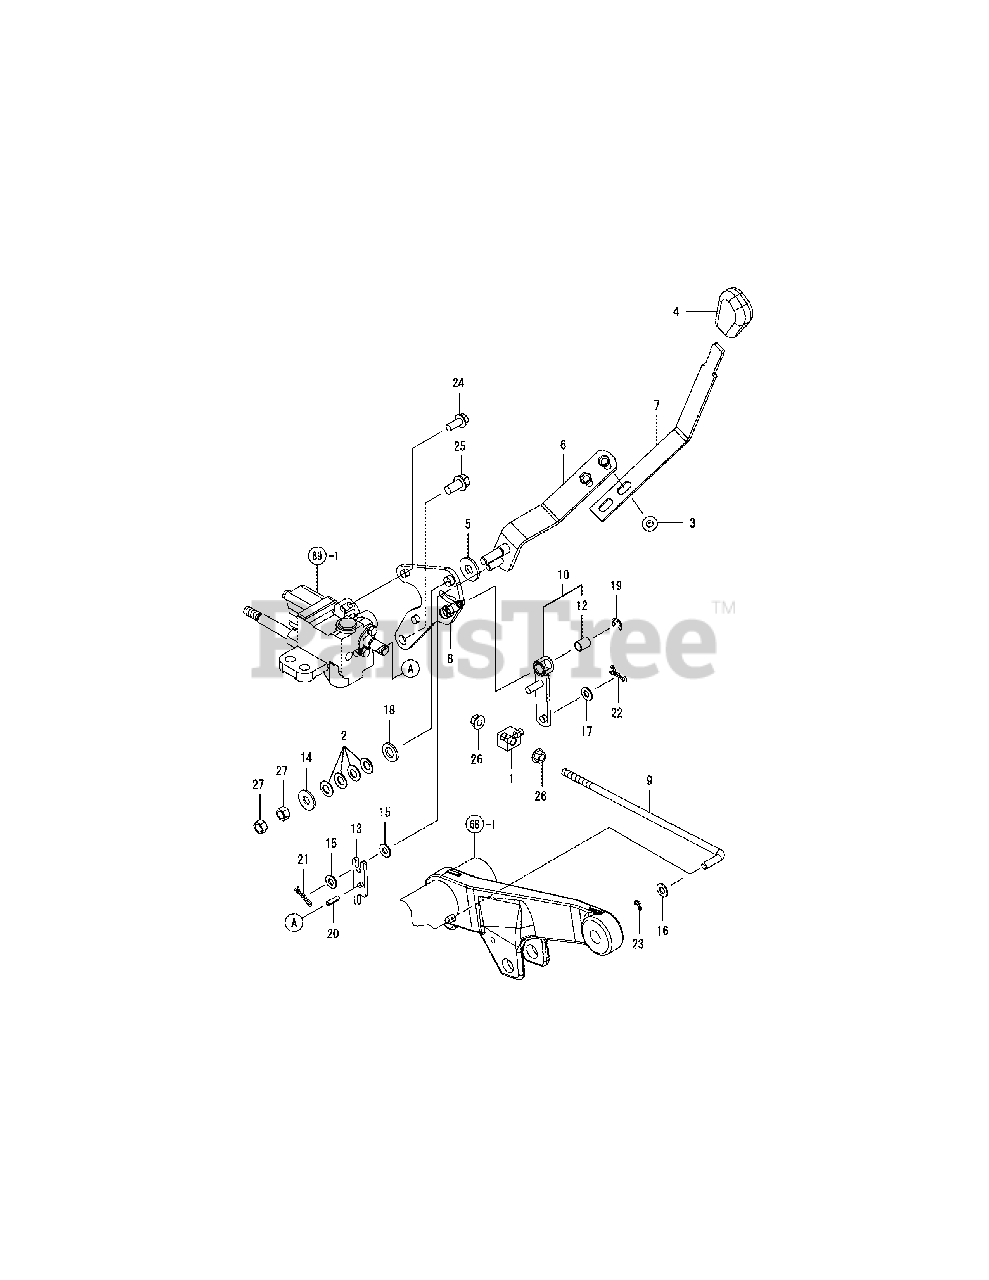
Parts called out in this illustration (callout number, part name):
2	Washer, Conical 10
5	Plate, Friction
6	Lever Cmp, Position
7	Lever, Position
8	Stay Cmp, Hyd. Link
10	Lever Asy, Control
12	Bearing, 10 X 15
20	Pin, 5.0A X 18
24-1	Bolt M 8X 16 Plated
